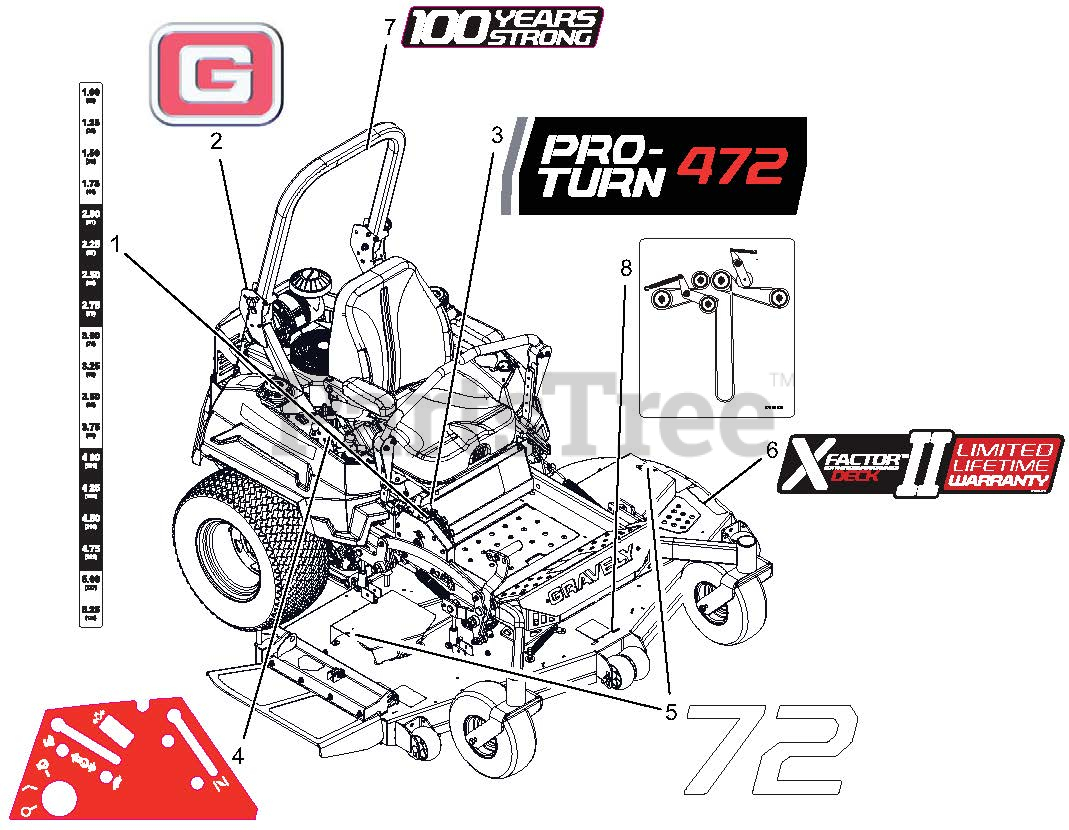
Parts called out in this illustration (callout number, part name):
1	DECAL, PT400 HEIGHT OF CUT
2	DECAL, GRAVELY BRAND
3	DECAL, PRO-TURN 472
4	DECAL, NON-EFI CONTROL PANEL
5	DECAL, 72"
6	DECAL, X-FACTOR DECK
7	DECAL, GRAVELY 100 YEAR
8	DECAL, BELT ROUTE RH BK SIDE IDLER
